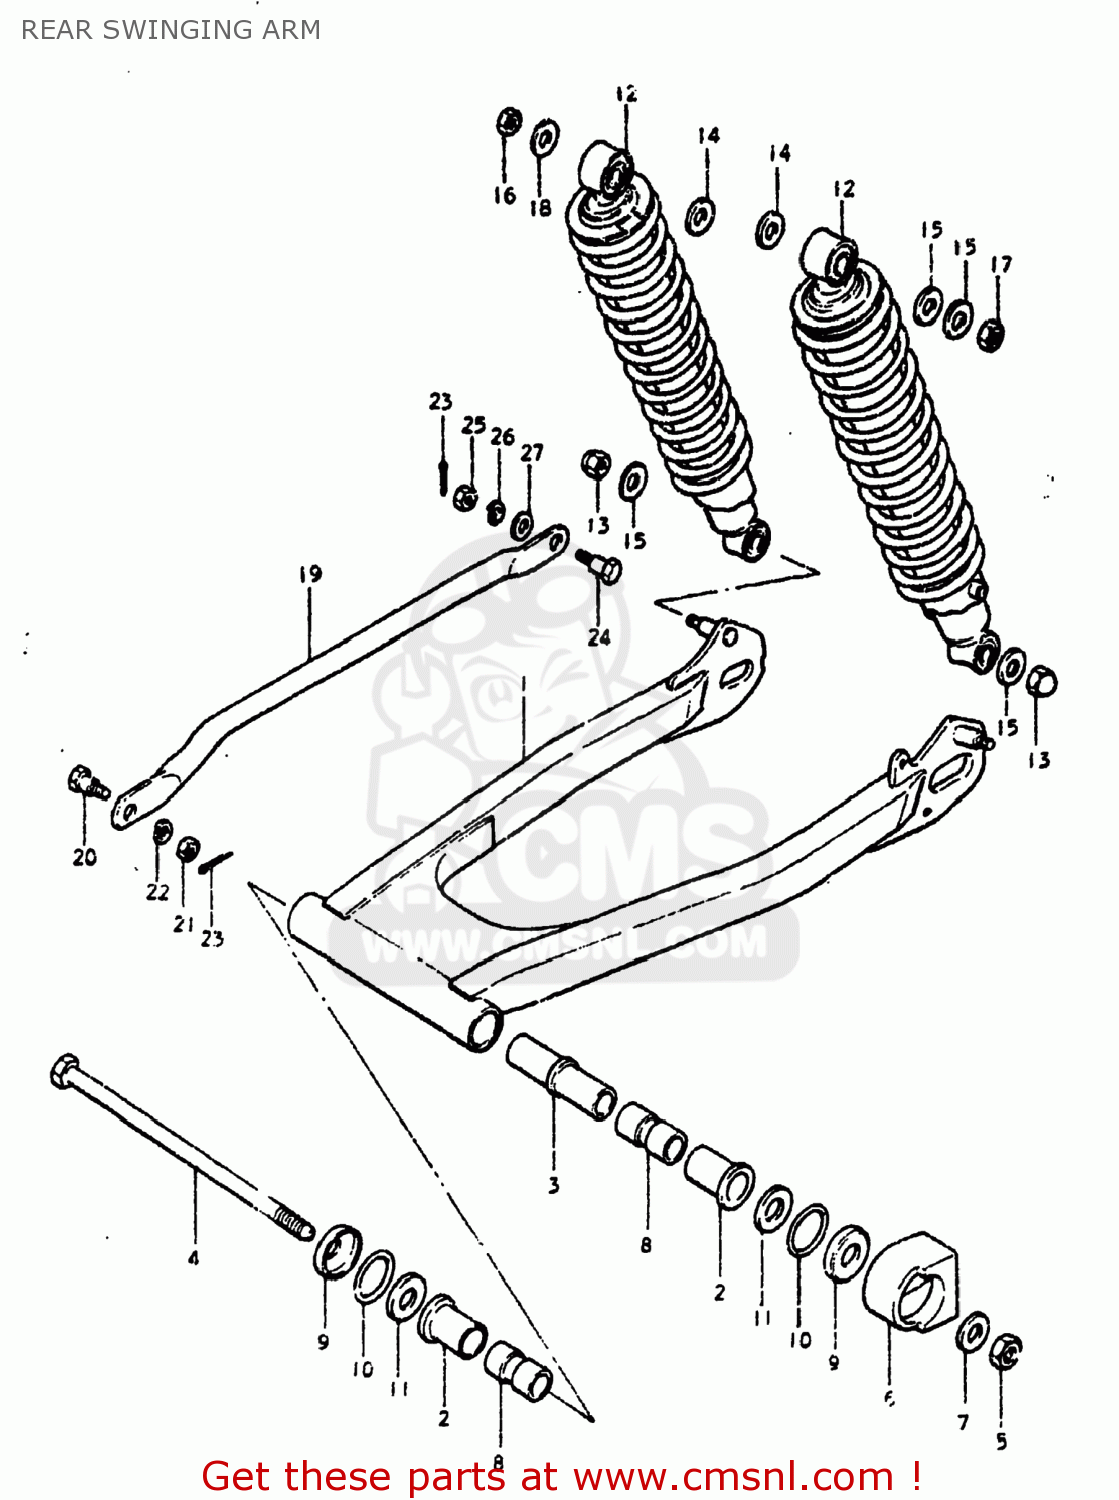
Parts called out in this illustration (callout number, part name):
1	SWING ARM ASSEMBLY,REAR
2	BUSH
3	SPACER,SWING ARM,CENTER
4	SHAFT,REAR SWING ARM
5	NUT 14MM
6	BUFFER,CHAIN TOUCH DEFLECTOR
7	WASHER
8	SPACER
9	COVER
10	O RING(D:3,ID:29.5)
11	WASHER(14.5X29X2.3)
12	ABSORBER ASSEMBLY,REAR SHOCK
13	NUT, LOWER LH
14	WASHER
15	WASHER
16	NUT
17	NUT
18	WASHER (12.5X24X3.2)
19	TORQUE LINK,REAR
20	BOLT(8X22.5)
21	NUT
22	LOCK WASHER
23	PIN
24	BOLT(10X32.5)
25	NUT
26	LOCK WASHER
27	WASHER
